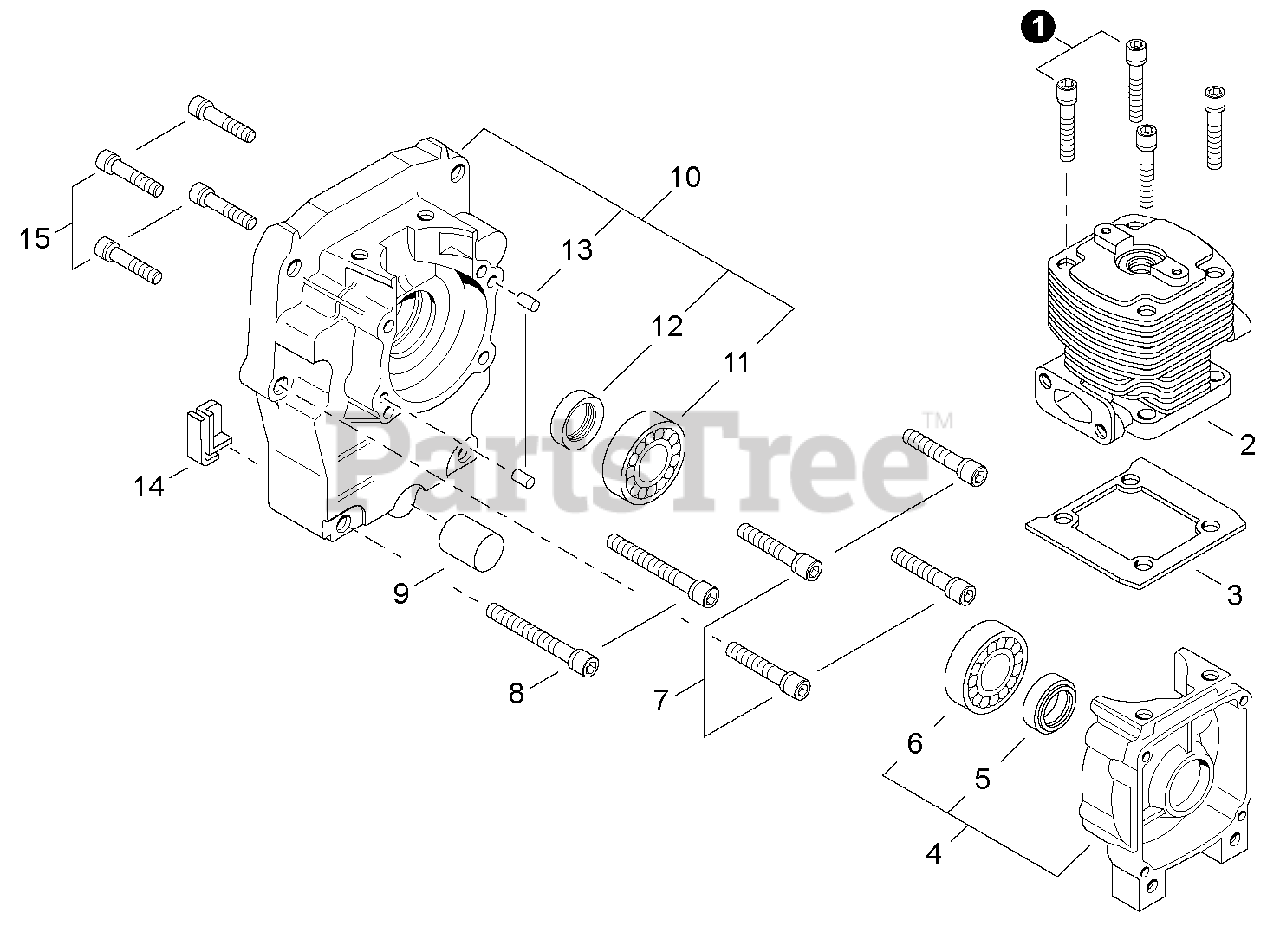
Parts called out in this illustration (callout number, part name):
1	SCREW - 5
2	CYLINDER
3	GASKET, CYLINDER
4	CRANKCASE ASSY - REAR
5	SEAL, OIL - 15
6	BEARING, BALL - 6202C3
7	BOLT - 6X30
8	BOLT - 6X45
9	CUSHION
10	CRANKCASE ASSY - FRONT
11	BEARING, BALL - 6202C3
12	SEAL, OIL - 15
13	PIN - LOCATING
14	GROMMET
15	SCREW - 5X30
